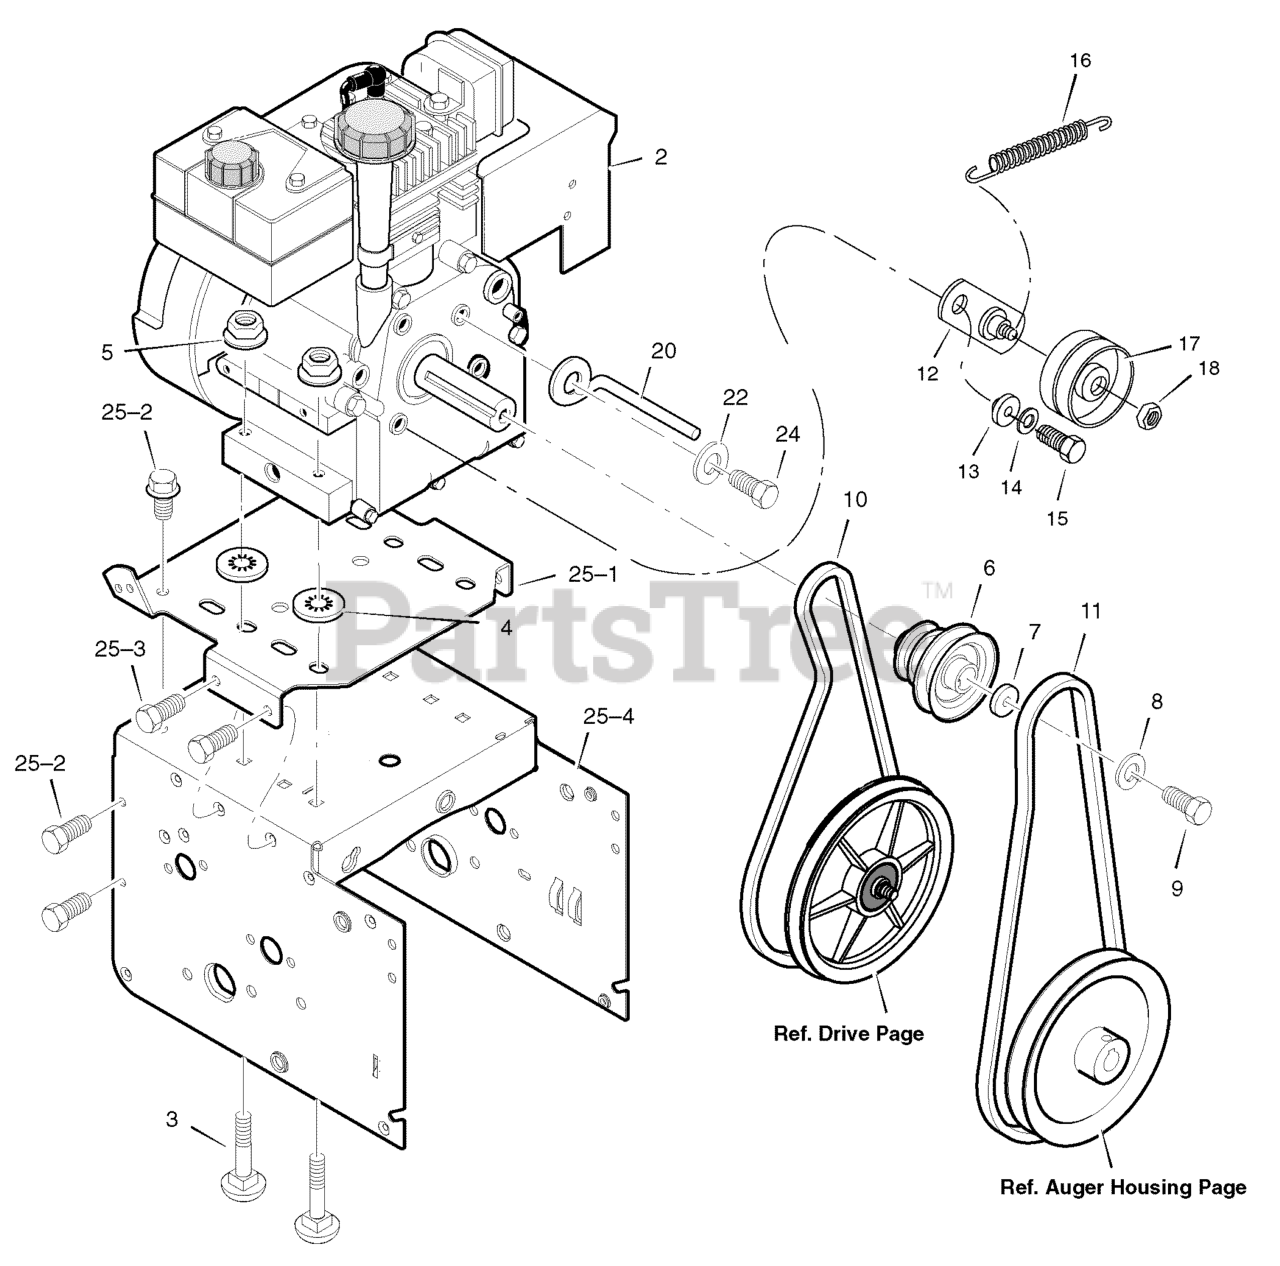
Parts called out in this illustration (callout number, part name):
2	ENGINE
3	BOLT, CARRIAGE 5/16-18
4	RETAINER, PUSH
5	NUT 5/16-18
6	PULLEY, ENGINE
7	WASHER
8	WASHER, SPLIT .38ID
9	SCREW, 3/8-24 x 1.00
10	BELT, V 3L 33.13LG
11	BELT, V 4L35.6 LG
12	BRACKET ASSEMBLY, IDLER
13	BUSHING, IDLER BRACKET
14	WASHER, SPLIT .31X.58X.08
15	SCREW, 5/16-24X .75
16	SPRING, IDLER TRACTION DRIVE
17	PULLEY, IDLER
18	NUT, JAM 3/8-16
20	GUIDE, ROD BELT
22	WASHER, SPLIT .31X.58X.08
24	SCREW, 5/16-24X .75
25	FRAME ASSEMBLY
25-1	PLATE, ENGINE MOUNT
25-2	SCREW 1/4-20 X .63
25-3	SCREW 5/16-18 X .50
25-4	FRAME, MOTOR BOX
